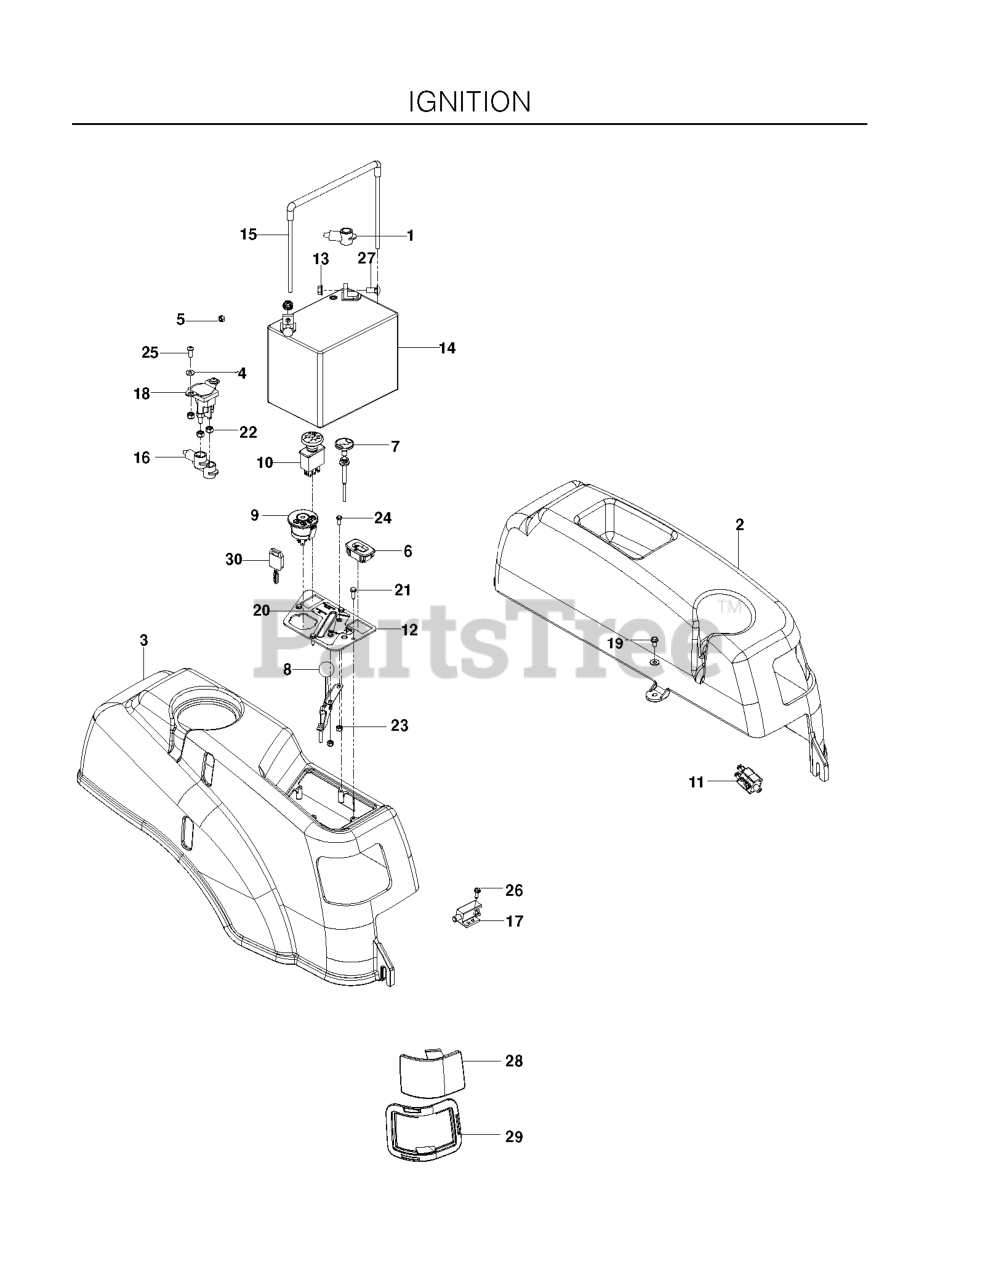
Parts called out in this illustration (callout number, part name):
2	FENDER, LT
3	FENDER, RT, GRAY
4	WASHER 1/4 INT TOOTH
5	JAM NUT 1/4C (2 2 PW01)
6	HOUR METER
7	CHOKE CABLE
8	THROTTLE CABLE
9	RP IGNITION SWITCH
10	RP.SWITCH, BLADE
11	SWITCH, BRAKE 3P
12	CONSOLE.PLATE.BLACK
13	5/16-18 NYLOC FLANGE NUT
14	BATTERY, 12 V 330 AMP
15	BATTERY TIE DOWN ASSEMBLY
16	TERMINAL COVER-SM
17	SWITCH, INTERLOCK
19	BOLT 1/4-20 X 1/2 HWST
20	DECAL, CTRL PANEL, HUSQ
21	HCS #10-24 X 1/2
22	NUT.1/4-20.HEX.NYLOC.ZD
23	NUT 10-24 NYLOC
24	SCR #10-12X3/4 HEX WAS HD ZD
25	SCR 1/4-20 X 5/8 BTN SKT HD ZD
26	SCREW #10 X 1/2 SELF TAPPING
27	BOLT 5/16C X 3/4" CARRIAGE
28	LENS, COLORED LEFT
29	LEFT HEADLIGHT RIM GREY
30	KEY
